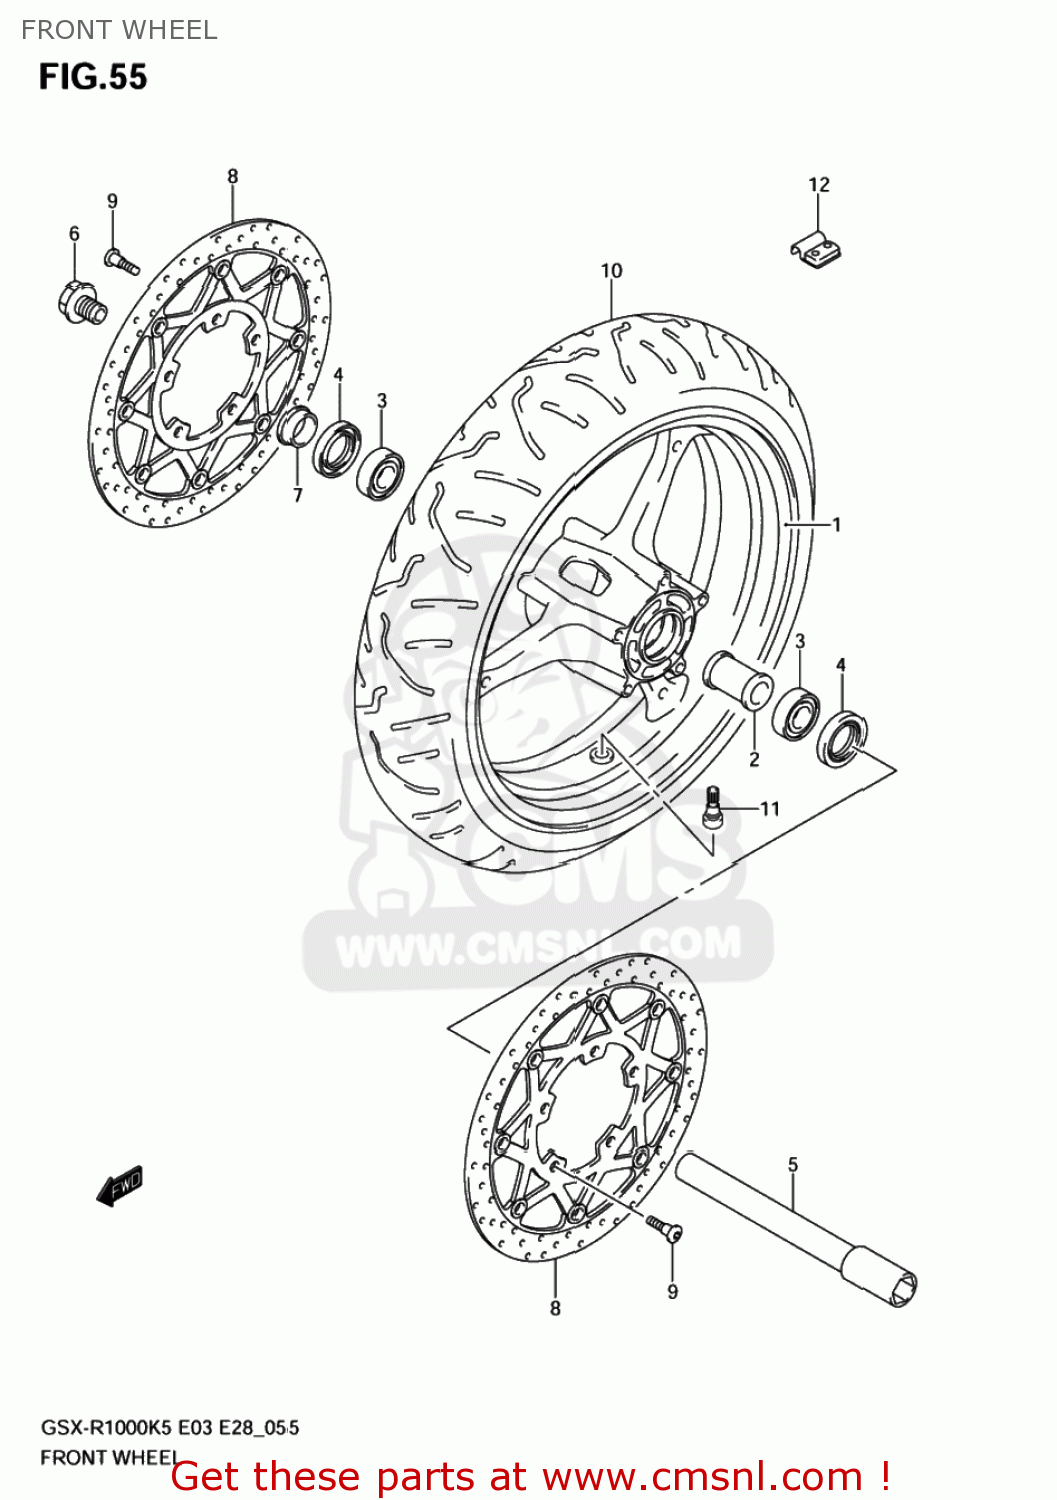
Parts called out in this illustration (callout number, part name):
1	WHEEL,FRONT(17
2	SPACER,FR HUB BEARING
3	BEARING(25X52X15)
4	SEAL,OIL(32X52X7)
5	AXLE,FR
6	BOLT,FRONT AXL
7	SPACER,FRONT A
8	DISC,FR BRAKE
9	BOLT(8X21)
10	TIRE, FRONT, 120/70ZR17 M/C (BRIDGESTONEBT014 F RADIAL J)
11	VALVE ASSY,WHEEL RIM(TR412)
12	WEIGHT,WHEEL BALANCE 10G
